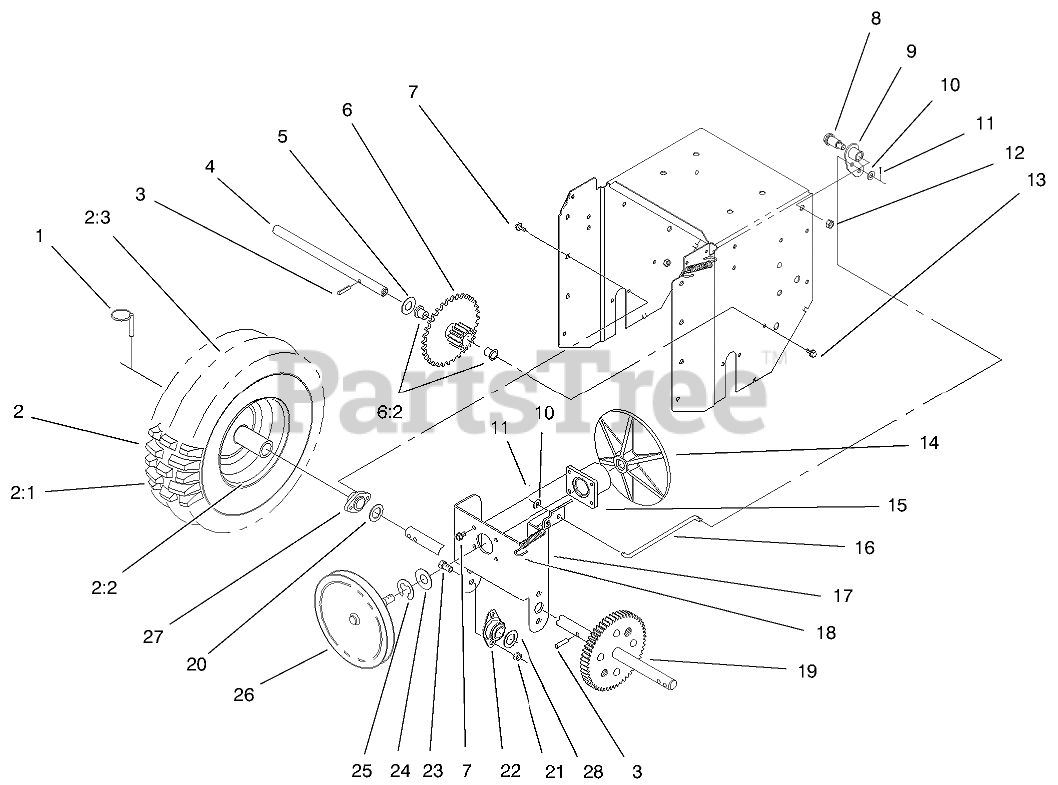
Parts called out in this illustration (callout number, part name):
1	PIN-LYNCH
2	ASM-Wheel
2:2	RIM-WHEEL
2:3	TUBE-INNER
3	PIN-ROLL, SLOTTED
4	SHAFT-INTERMEDIATE
5	WASHER
6	GEAR/BUSHING ASM
6:2	Bushing (Only On: 38083)
7	SCREW-HWH
8	BOLT-SHOULDER
9	HUB-PIVOT
10	WASHER-FLAT
11	PIN-COTTER
12	NUT-LOCK, NI
13	SCREW-HWHTF
14	DISC-FRICTION
15	BEARING HUB ASM
16	ROD-ENGAGE
17	FRAME-FRICTION PLATE
18	SPRING-ENGAGE
20	WASHER-THRUST
21	NUT-LOCK, NI
22	BUSHING
23	SCREW-HH
24	WASHER-THRUST
25	RING-RETAINING, EXT
26	PULLEY/SHAFT ASM
27	BEARING-AXLE
28	WASHER-THRUST
